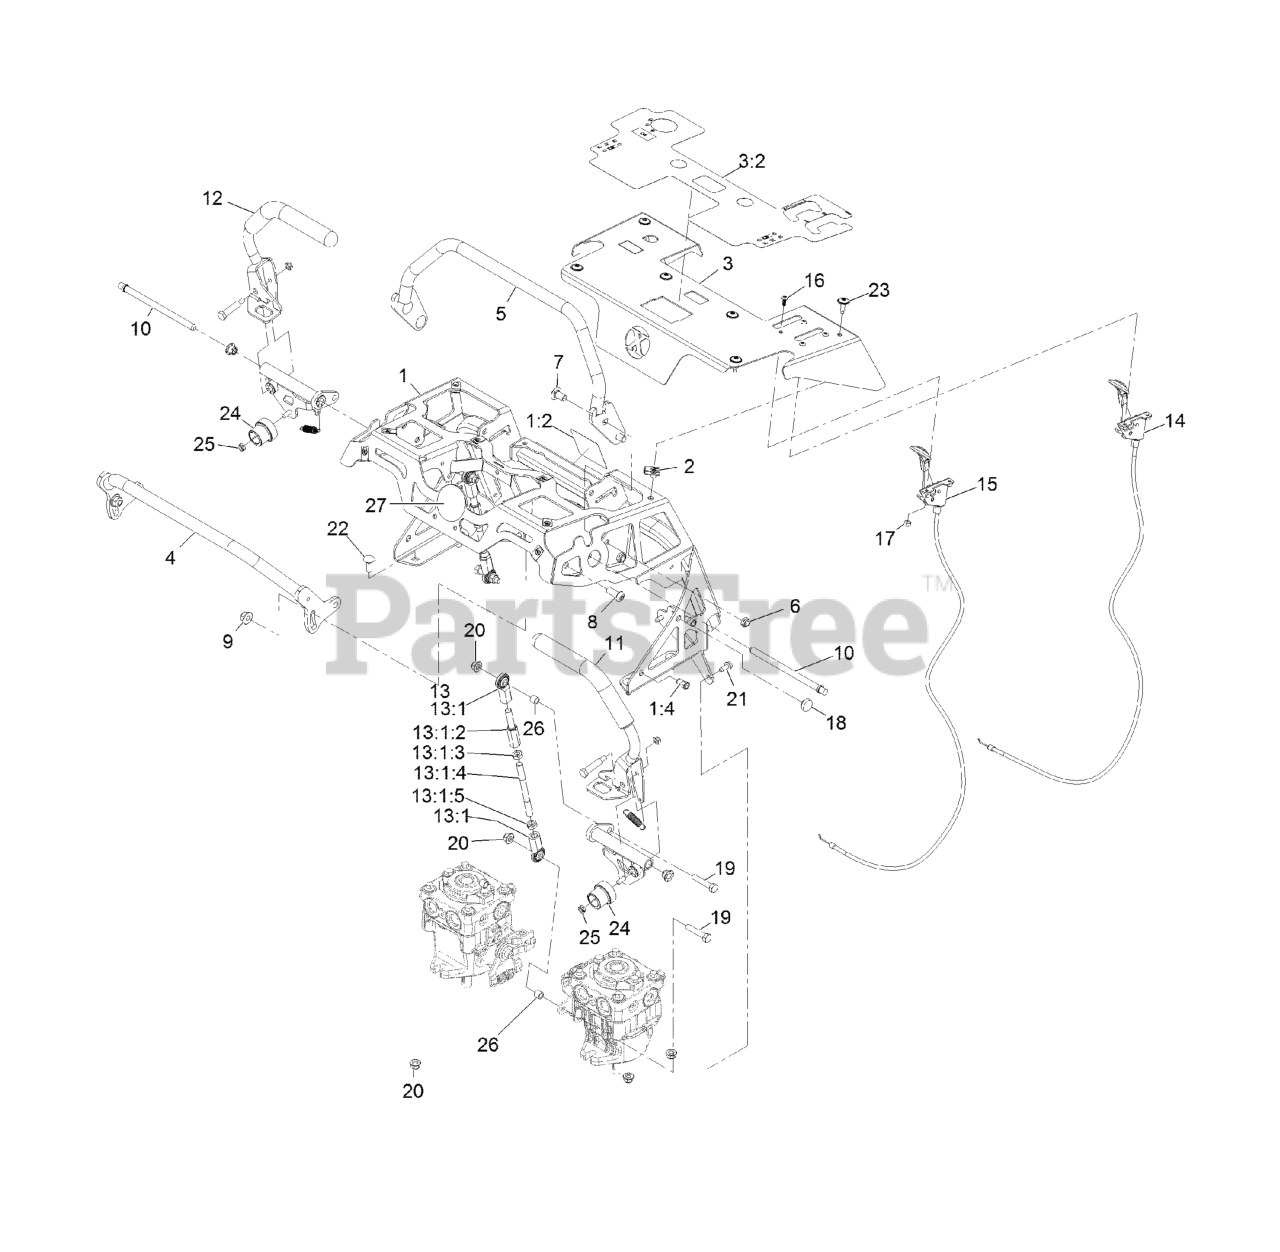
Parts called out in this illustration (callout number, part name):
1	ASM-CTRL TOWER
1:2	DECAL-WARNING
1:4	NUT-CLINCH,HEX
3	ASM, CONTROL PANEL W/ DECALS
3:2	DECAL-CONTROL PANEL NON-EFI
4	WELD, FRONT REF BAR
5	WELD, REAR REF BAR
7	SCREW-CARR
8	SCREW-HSBH
9	NUT-HF, NI
10	PIN, PIVOT
11	ASM, MOTION CONTROL, LT
12	ASM, MOTION CONTROL, RT
13	ASM, LINKAGE
13:1	ASM, Motion Control Link
13:1:2	ROD-ADJUSTMENT
13:1:3	NUT-HEX JAM, LH
13:1:5	NUT-HJ
14	CONTROL, CHOKE
15	CONTROL, THROTTLE
16	SCREW, BHCS
17	NUT-LOCK, NI
19	SCREW-HH
20	NUT-HF, NI
21	SCREW-HWH
22	SCREW-CARR
23	SCREW, TORX
25	NUT-LOCK, NI
27	DECAL-COVER
